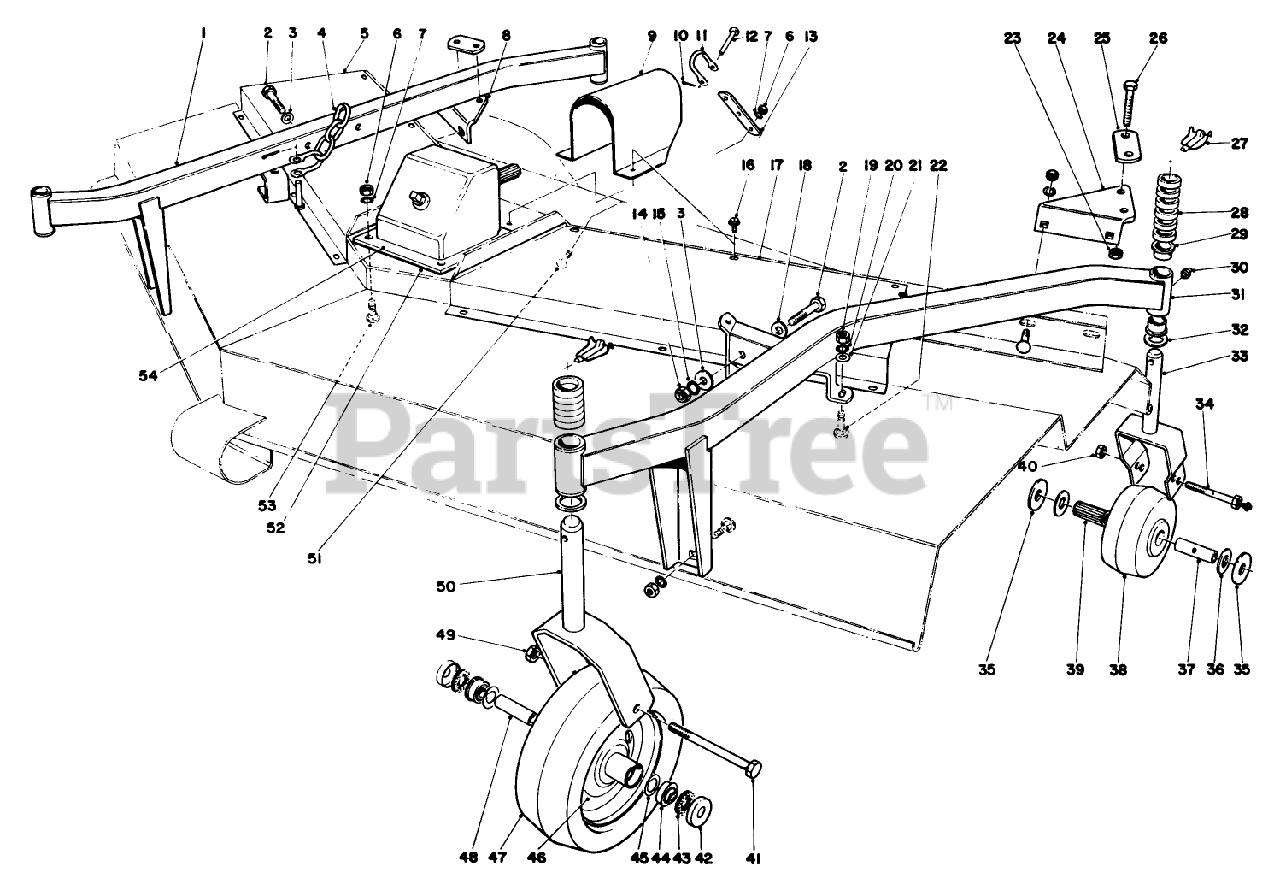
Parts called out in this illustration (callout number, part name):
1	Caster Arm R.H. (Incl. Ref. #29)
2	SCREW-HH
3	WASHER-FLAT
4	Lift Chain
5	RH DECK COVER R
6	NUT-HEX
7	WASHER-LOCK
8	Bracket-Clamp
9	Shroud Universal
10	PIN-COTTER
11	SHACKLE
11	STUD-IDLER
12	PIN-CLEVIS
13	Lift Strap
14	NUT-HEX
15	WASHER-LOCK
16	SCREW-HHF
17	LH DECK COVER R
18	WASHER-FLAT
19	NUT-HH
20	WASHER-LOCK
21	WASHER-FLAT
22	SCREW-CARR
23	NUT-LOCK, NI
24	Bracket-Clamp
25	Bar-Caster Clamp
26	SCREW-HH
27	PIN-LYNCH
28	SPACER 1/2 IN
29	Bushing
30	FITTING-GREASE
31	Caster Arm L.H. (Incl. Ref. #29)
32	WASHER-THRUST
33	Caster Fork Rear
34	AXLE ASM
35	WASHER
36	BEARING RETAINER
37	SPANNER BUSHING
38	WHEEL
39	ROLLER BRG W/46-8960
40	NUT-LOCK
41	SCREW-HH
42	AXLE SLINGER B
43	WASHER
44	.500 RF BALL BEARING
45	WASHER
46	Caster Wheel & Tire (Incl. Ref. #47)
48	SPACER
49	NUT-HEX
50	Caster Fork
51	SCREW-CARR
52	SPACER R
53	SCREW-CARR
54	GEAR BOX ASM
